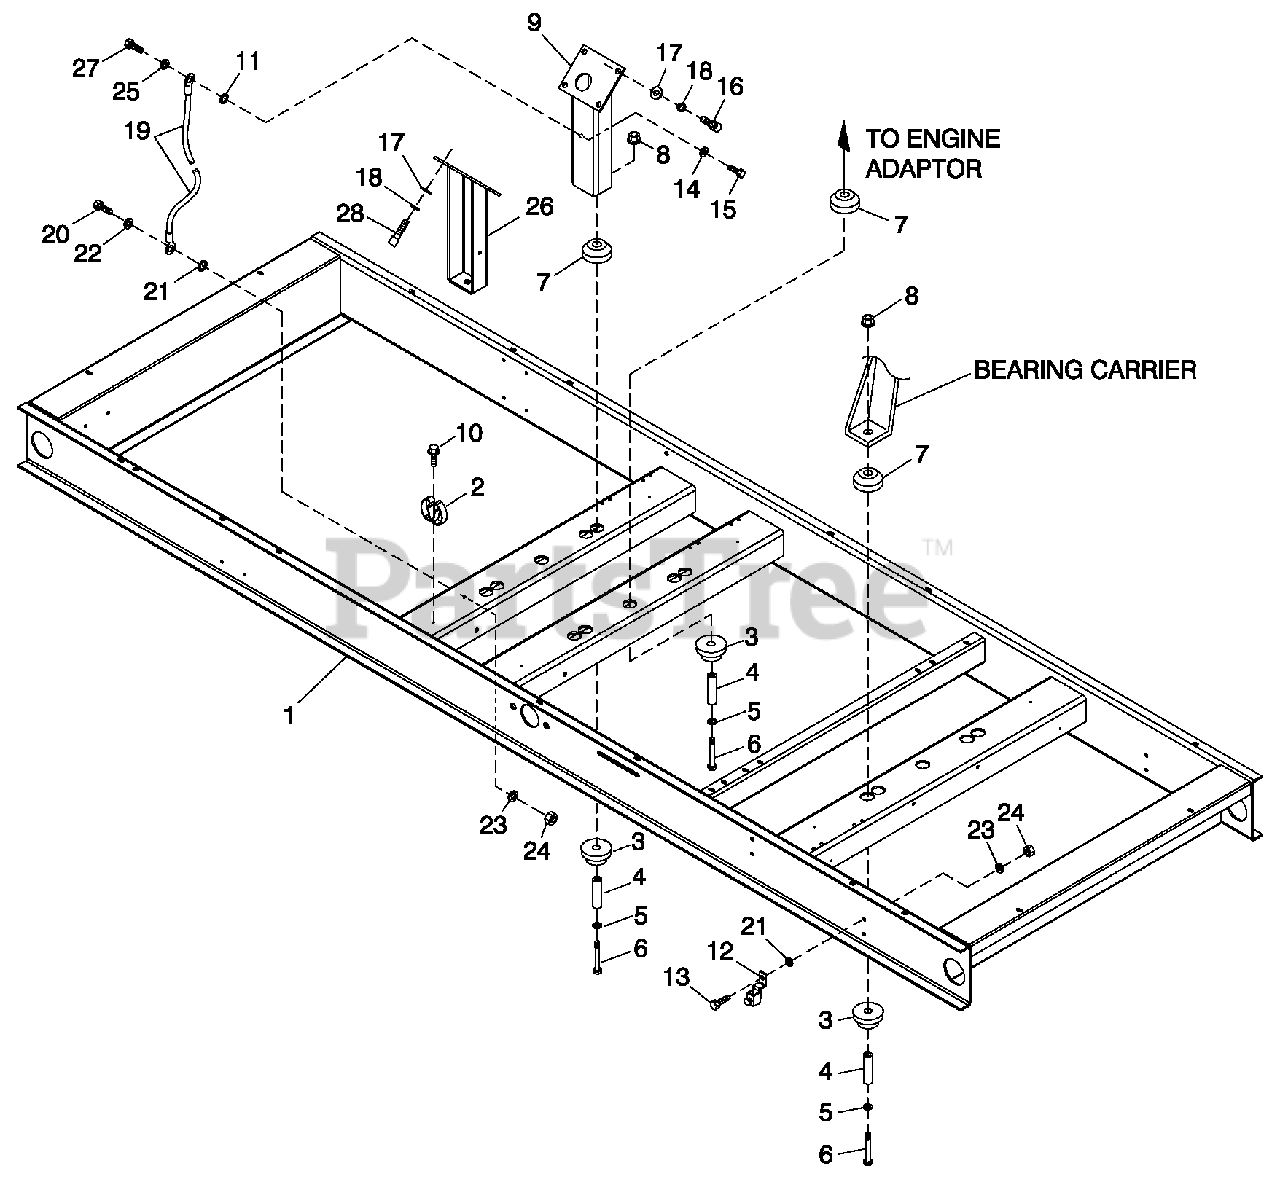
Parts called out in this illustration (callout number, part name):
1	BASE CPL 150KW 2P
2	SPRING CLIP HOLDER .37-.62
3	DAMPENER VIBRATION
4	SPACER .49 X .62 X 1.87 PWDR/ZINC
5	WASHER FLAT M12
6	SCREW HHC M12-1.75 X 85 G8.8
7	DAMPENER VIBRATION 50 WHITE
8	NUT LOCKING M12-1.75
9	SUPPORT ENG 5.4L LH/RH 6.8L RH
10	SCREW HHTT M4-0.7 X 8 BP
11	WASHER SHAKEPROOF INT 1/4
12	LUG SOLDERLESS 3/0-#4 X 13/32 CU
13	SCREW HHC M8-1.25 X 25 G8.8
14	WASHER FLAT 1/4-M6 ZINC
15	NUT HEX M6 X 1.0 G8 YEL CHR
16	SCREW SHC M10-1.5 X 30 G12.9
17	WASHER FLAT 3/8-M10 ZINC
18	WASHER LOCK M10
19	WIRE ASSEM #4GA GRD
20	SCREW HHC M8-1.25 X 30 G8.8
21	WASHER SHAKEPROOF INT 3/8
22	WASHER LOCK M8-5/16
23	WASHER FLAT 5/16-M8 ZINC
24	NUT HEX M8-1.25 G8 YEL CHR
25	WASHER LOCK M6-1/4
26	SUPPORT, ENGINE 6.8L LH SIDE
27	SCREW HHC M6-1.0 X 30 G8.8
28	SCREW SHC M10-1.5 X 60 G12.9
